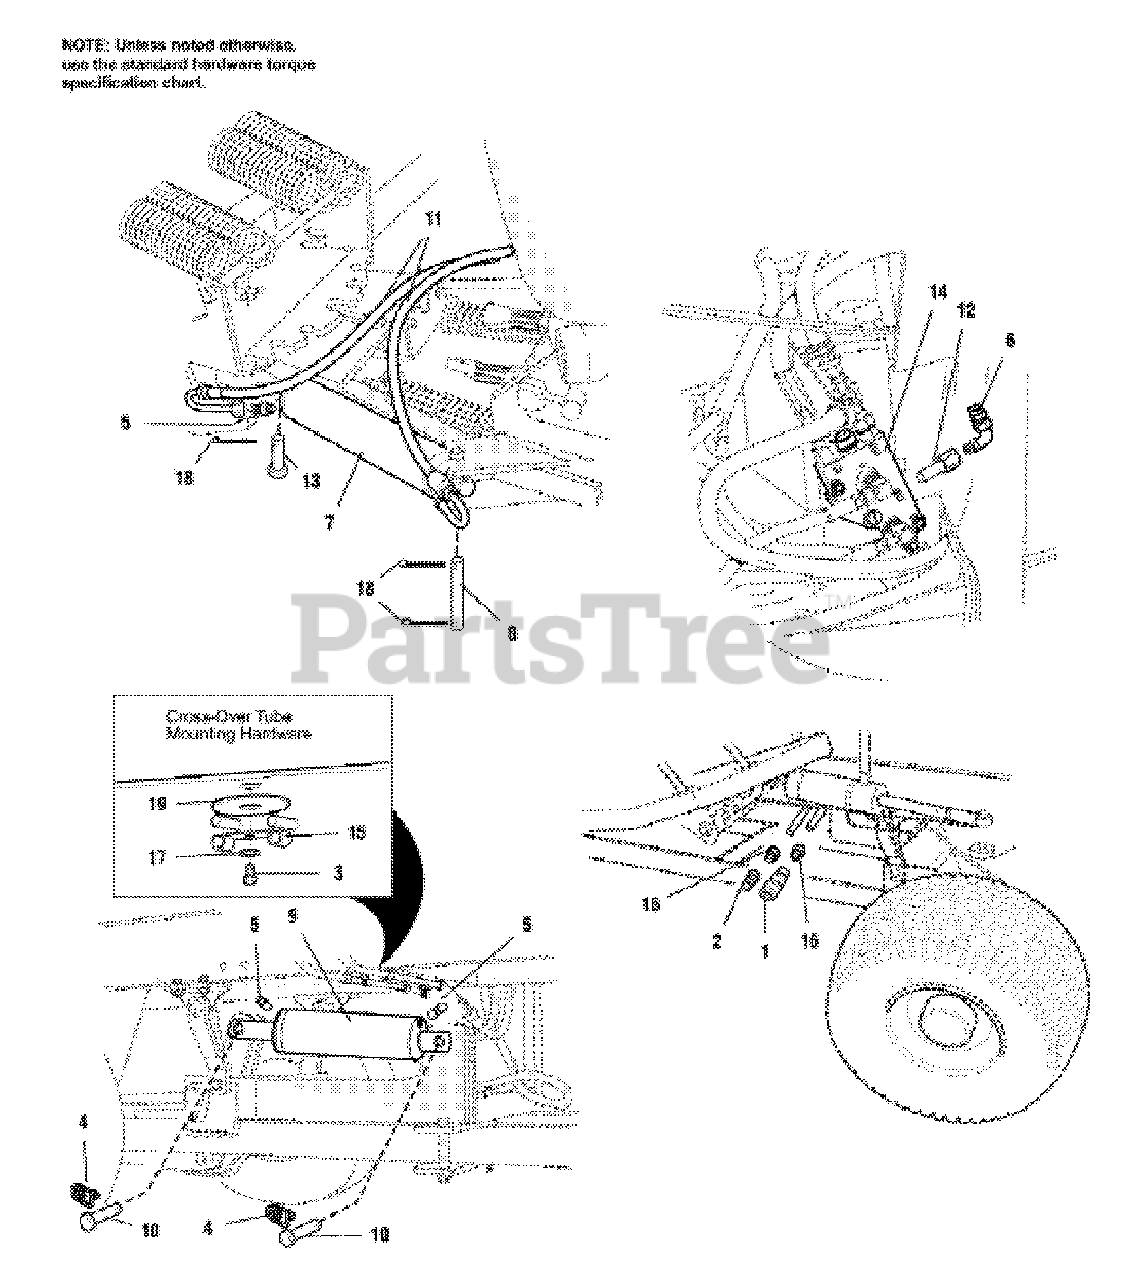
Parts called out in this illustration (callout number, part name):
1	LEVER ASSEMBLY
2	TIE, Self-Locking
3	FITTING, Cylinder, Male
4	CYLINDER, Lift
5	CLIP, Safety
6	PIN, Clevis
7	SUPPORT ASSEMBLY
8	HOSE, Hydraulic, 1/2" x 67"
9	HOSE, Hydraulic, 1/2 x 69"
10	FITTING, Tube, Male, Tall
11	FITTING, Tube, Male, Short
12	VALVE ASSEMBLY, Two-Spool
13	CAPSCREW, Hex Hd, 1/2-13 x 1-1/2
14	WASHER, Lock, 1/2
15	NUT, Hex, 1/2-13
16	FITTING, Tube, Male
17	LOCKWASHER, 5/16
18	PIN, Cotter
19	WASHER, Large 5/16
